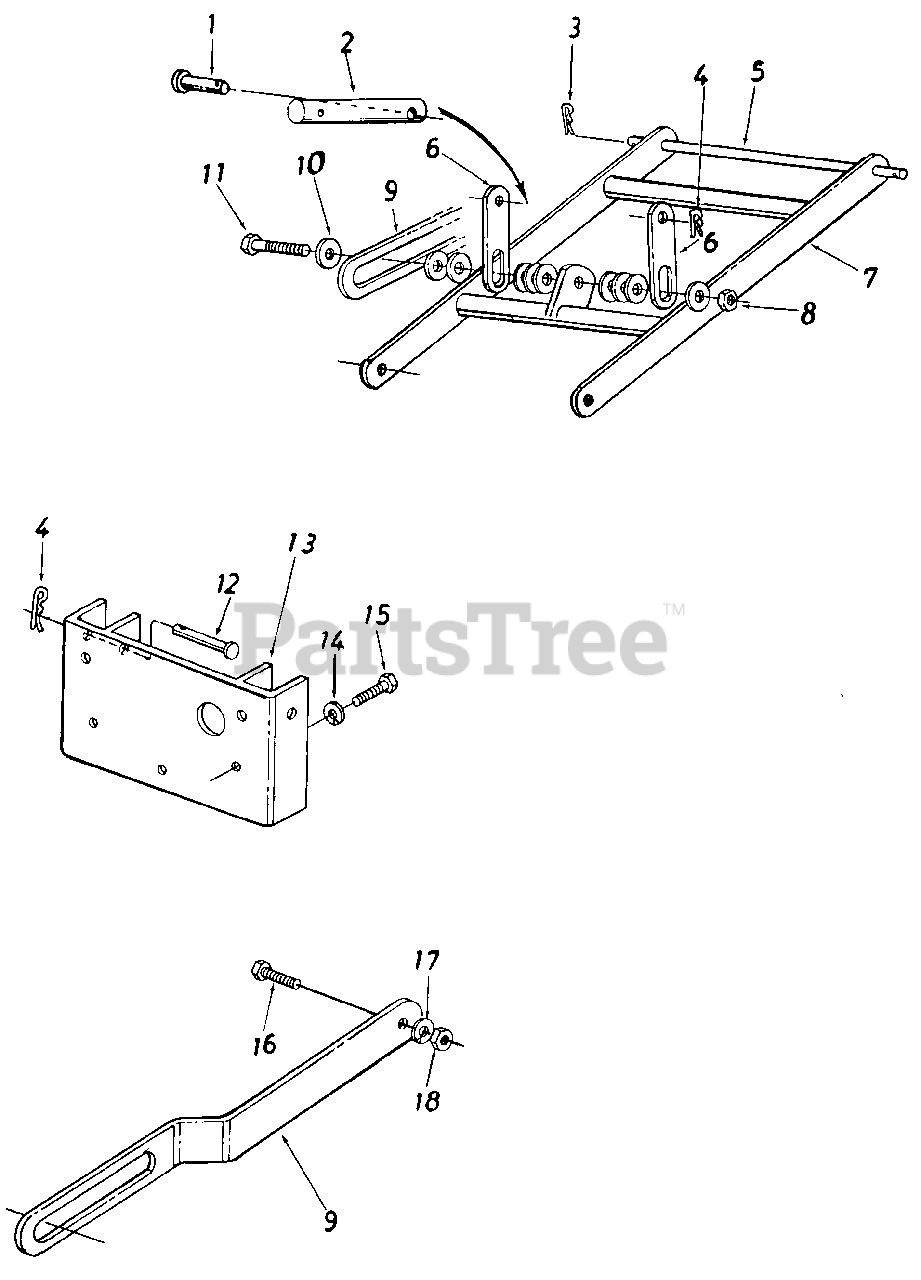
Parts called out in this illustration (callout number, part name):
1	Clevis Pin 1/2" Dia. x 2.17" Lg.
2	Hitch Shaft
3	Internal Cotter Pin
4	Hair Pin Cotter
5	Hitch Rod
7	Hitch Bar Ass'y.
8	Hex L.-Nut 1/2-13 Thd.
9	Stabilizer Link
10	Fl.-Wash. 1/2" I.D. x .93" O.D. (10 Req'd)
11	Hex Bolt 1/2-13 x 3" Lg.
12	Clevis Pin5/8" Dia.3-1/16" Lg.
13	Mounting Plate Ass'y.
14	L.-Wash. 3/8" I.D.
15	Hex Bolt 3/8-16x 1.25" Lg. (Grade 5)
16	Shoulder Bolt 4.35" Dia. x .265
17	L.-Wash. 5/16" I.D.
18	Hex Nut 5/16-18 Thd.
